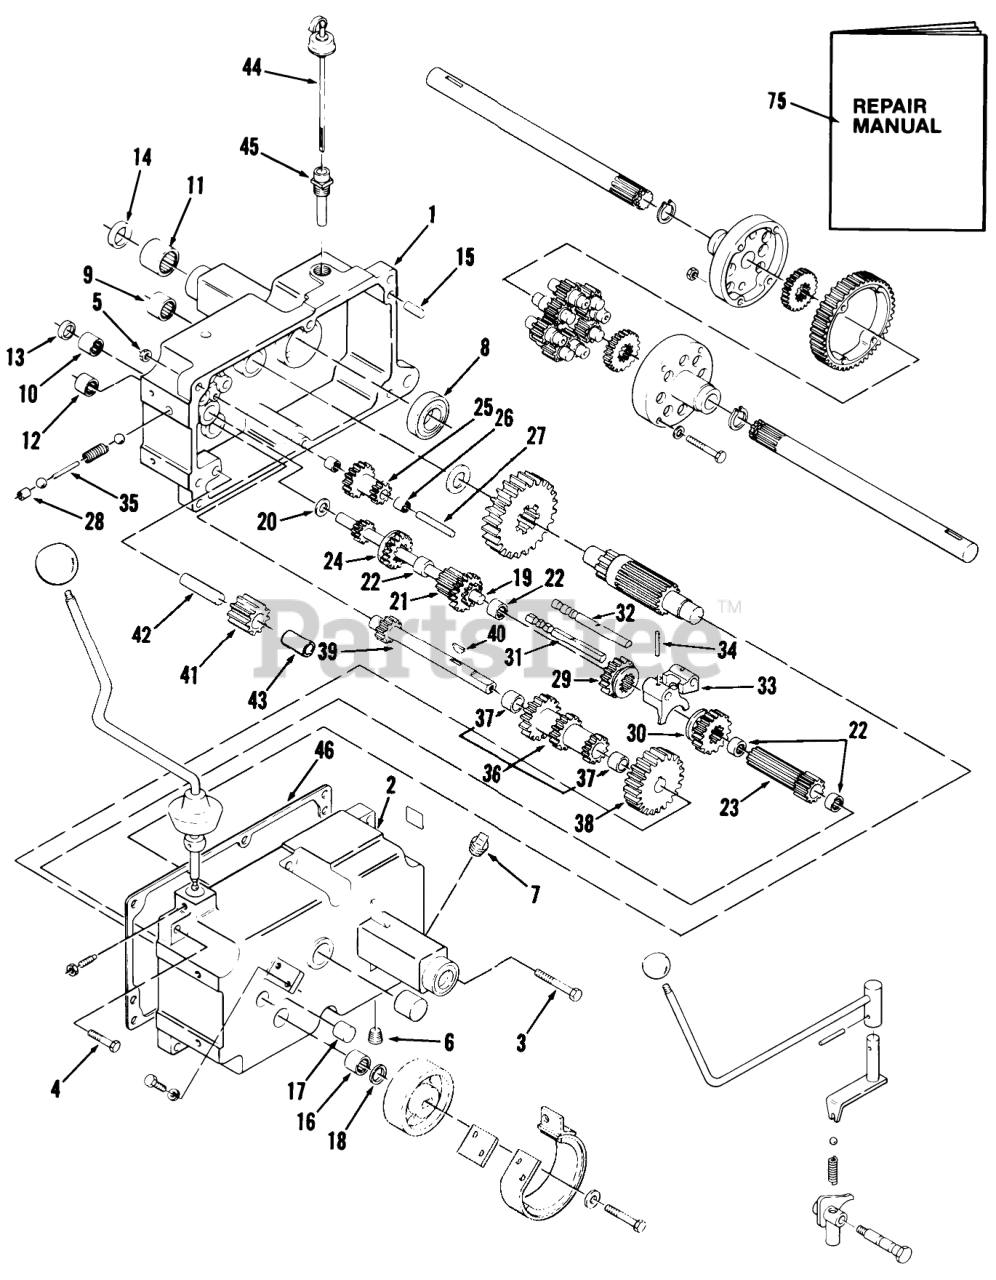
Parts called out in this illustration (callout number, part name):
1	Case RH
2	Case L.H.
3	HHCS
4	Bolt
5	Nut
6	PLUG 1/4 PIPE ALLEN
7	Plug
8	BALL BRG 1 1/2 I.D.
9	BEARING-NEEDLE
10	BEARING-NEEDLE
11	BEARING
12	BEARING-NEEDLE
13	SEAL-OIL
14	SEAL-OIL
15	PIN-DOWEL
16	BEARING-NEEDLE
17	Bearing Needle
18	SEAL-OIL
19	SHAFT-INPUT
20	WASHER-THR
21	GEAR
22	BEARING-NEEDLE
23	GEAR
24	GEAR-SLIDING
25	Gear
26	BEARING-NEEDLE
27	GEAR-SHAFT REDUCTION
28	CUP-PLUG
29	GEAR-HI AND 2ND
30	GEAR-LOW AND REVERSE
31	RAIL-SHIFT
32	RAIL-REAR SHIFT
33	FORK-SHIFT
34	PIN-ROLL
35	PIN-SHIFT
36	GEAR-CLUSTER
37	BUSHING-BRONZE
38	GEAR-CLUSTER SHAFT
39	Cluster Shaft
40	KEY-WOODRUFF
41	GEAR/BUSHING ASM-REVERSE IDLER
42	PIN-DIFFERENTIAL
43	BUSHING
44	ASSY-DIPSTICK
45	NIPPLE-TRANS FILL
46	GASKET-TRANSMISSION
